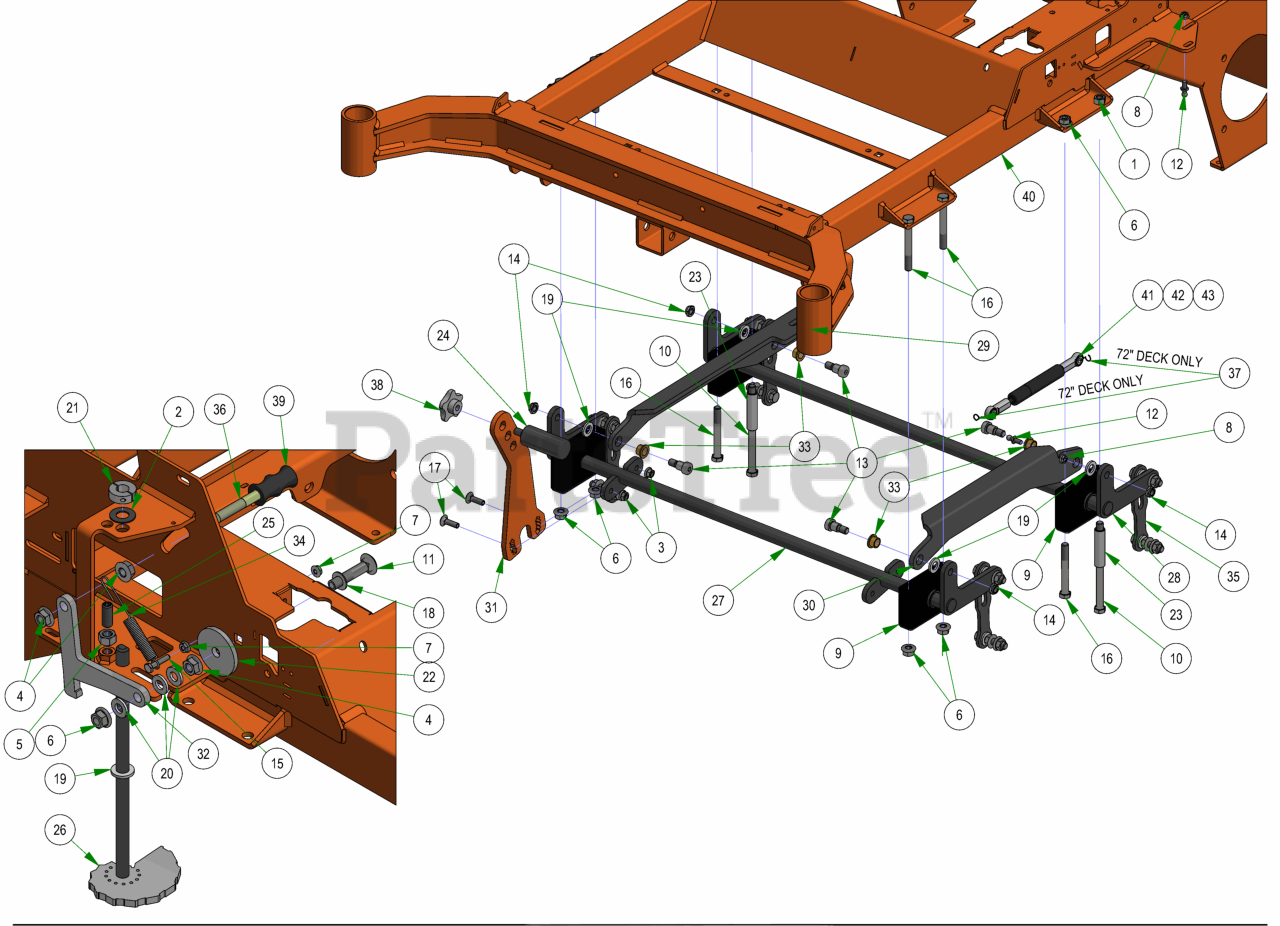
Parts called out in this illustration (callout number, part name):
1	1/2-13 HEX 2-WAY REVERSIBLE CENTER LOCKNUT Grade B ZINC
2	.625 ID x 1.250 OD x .062 THK F/W Nylon
3	3/8-16 NYLON INSERT FLANGE LOCKNUT (GR.F) ZINC
4	1/2-13 HEX SERRATED FLANGE NUT HARD/ZINC
5	1/2-13 HEX NUT ZINC
6	1/2-13 NYLON INSERT FLANGE LOCKNUT ZINC
7	1/4-20 HEX SERRATED FLANGE NUT HARD/ZINC
8	5/16-18 HEX SERRATED FLANGE NUT HARD/ZINC
9	Pillow Block Assembly
10	1/2-13 X 7 HEX CAP SCREW (GR.5) ZINC
11	2 1/2 x 1/2 Carriage Bolt
12	10mm Damper Ball Stud-XP Linkage
13	5/8 X 5/8 SOCKET SHOULDER BOLT ZINC YELLOW
14	1/2-13 NYLON INSERT JAM LOCKNUT ZINC
15	1/4-20 X 1-1/4 HEX CAP SCREW (GR.5) ZINC
16	1/2-13 X 4 HEX CAP SCREW (GR.8) ZINC YELLOW
17	3/8-16 X 1-1/4 CARRIAGE BOLT ZINC
18	.517 SQ WDTH ID X .937 OD X .060 THICK F/W PHOS/OIL
19	.635 ID X 1.120 OD X .140 THICK FLAT WASHER NYLON
20	.505 ID X 1.000 OD X .125 THICK FLAT WASHER NYLON
21	5/8" Split Collar
22	MZ Deck Idler Spacer
23	2019 Deck Stop Spacer
24	Knurled Pedal
25	Dial Rod Plunger
26	2019 Outlaw Gen2 Deck Height Dial Rod Assy
27	2019 Outlaw Actuator - Front
28	2019 Outlaw Actuator - Rear
29	2019 Actuator Linkage – Right – Black
30	2019 Actuator Linkage - Left - Black
31	Foot Lift Upright Lever
32	2019 Outlaw Deck Travel Lock
33	.627 ID X .753 OD X .500 LGTH X 1.000 FLG OD X .094 FLG THICK FLANGED BEARING OIL-IMPREG BRNZ
34	Brake Spring
35	Deck Hanger Assembly
36	Seat Bracket Pin
37	Security Ring - PC744
38	Foot Pedal Knob 1/2-13
39	Travel Lock Rubber Grip
40	2023 Rebel Frame - Painted
41	200 lb Gas Spring- 54" Deck outlaw
42	250lb Gas Spring - 61" Deck
43	300lb Gas Spring - 72" Deck
